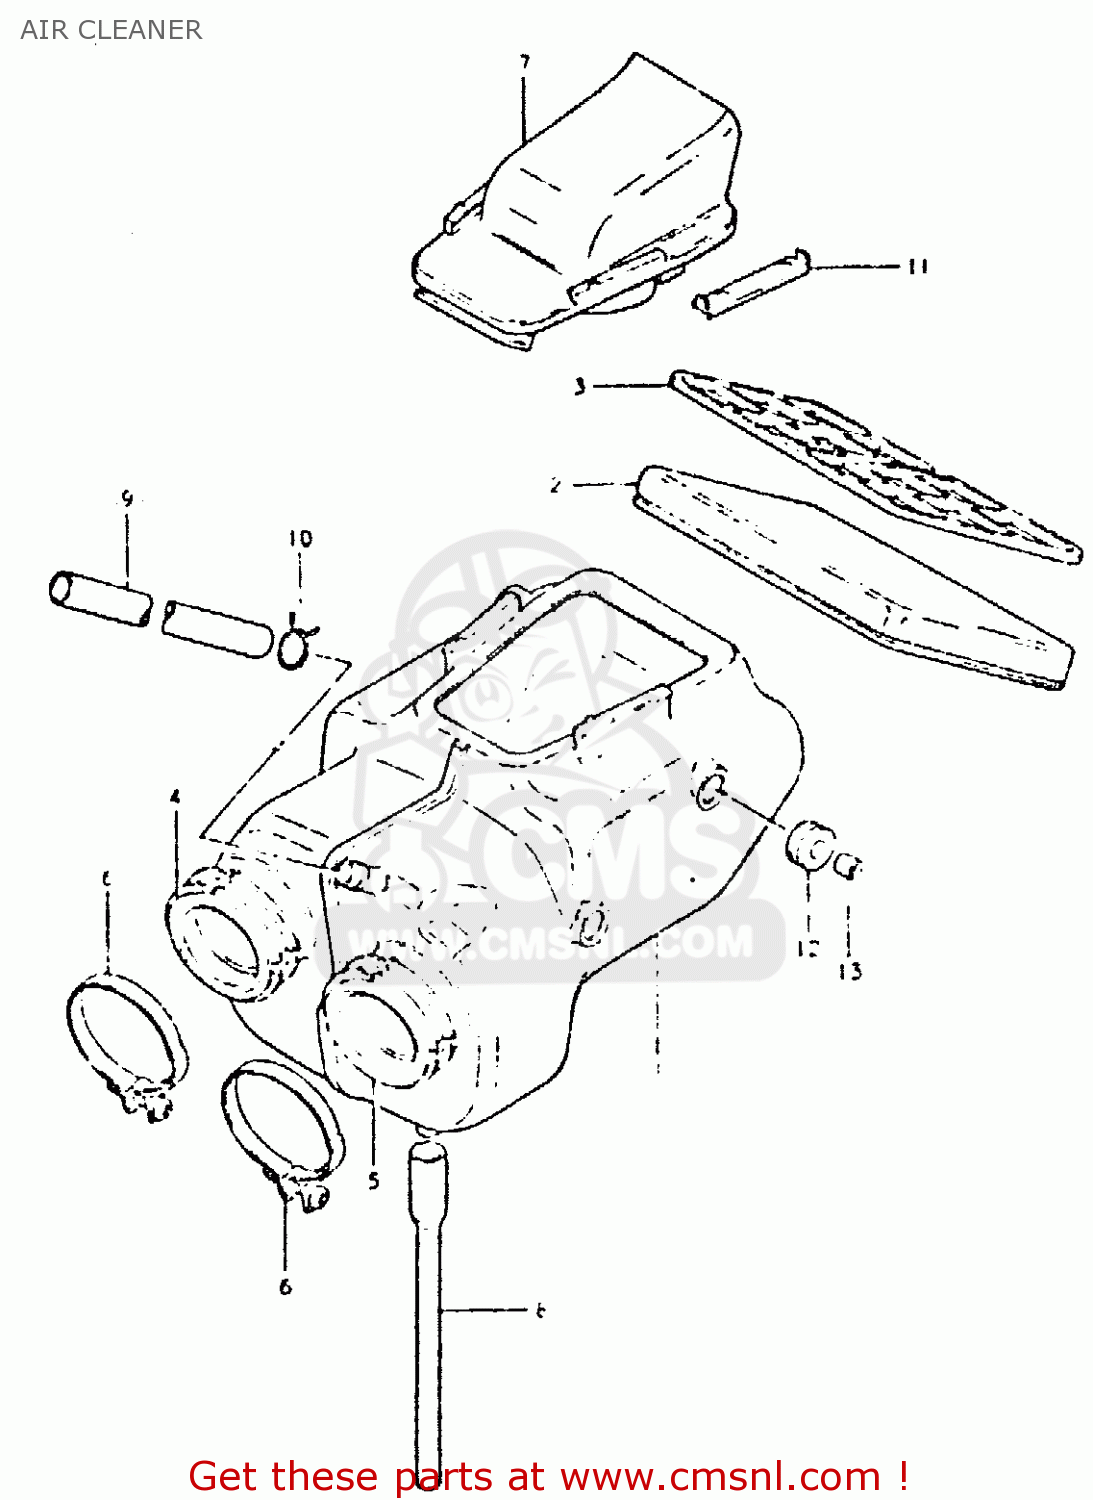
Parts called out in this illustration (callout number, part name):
1	CLEANER ASSEMBLY,AIR
2	FILTER
3	HOLDER NO.2
4	OUTLET,R
5	OUTLET,L
6	CLAMP
7	CAP
8	DRAIN TUBE
9	HOSE
10	CLAMP
11	SLIDER
12	CUSHION
13	SPACER(6.1X9X7.5)
